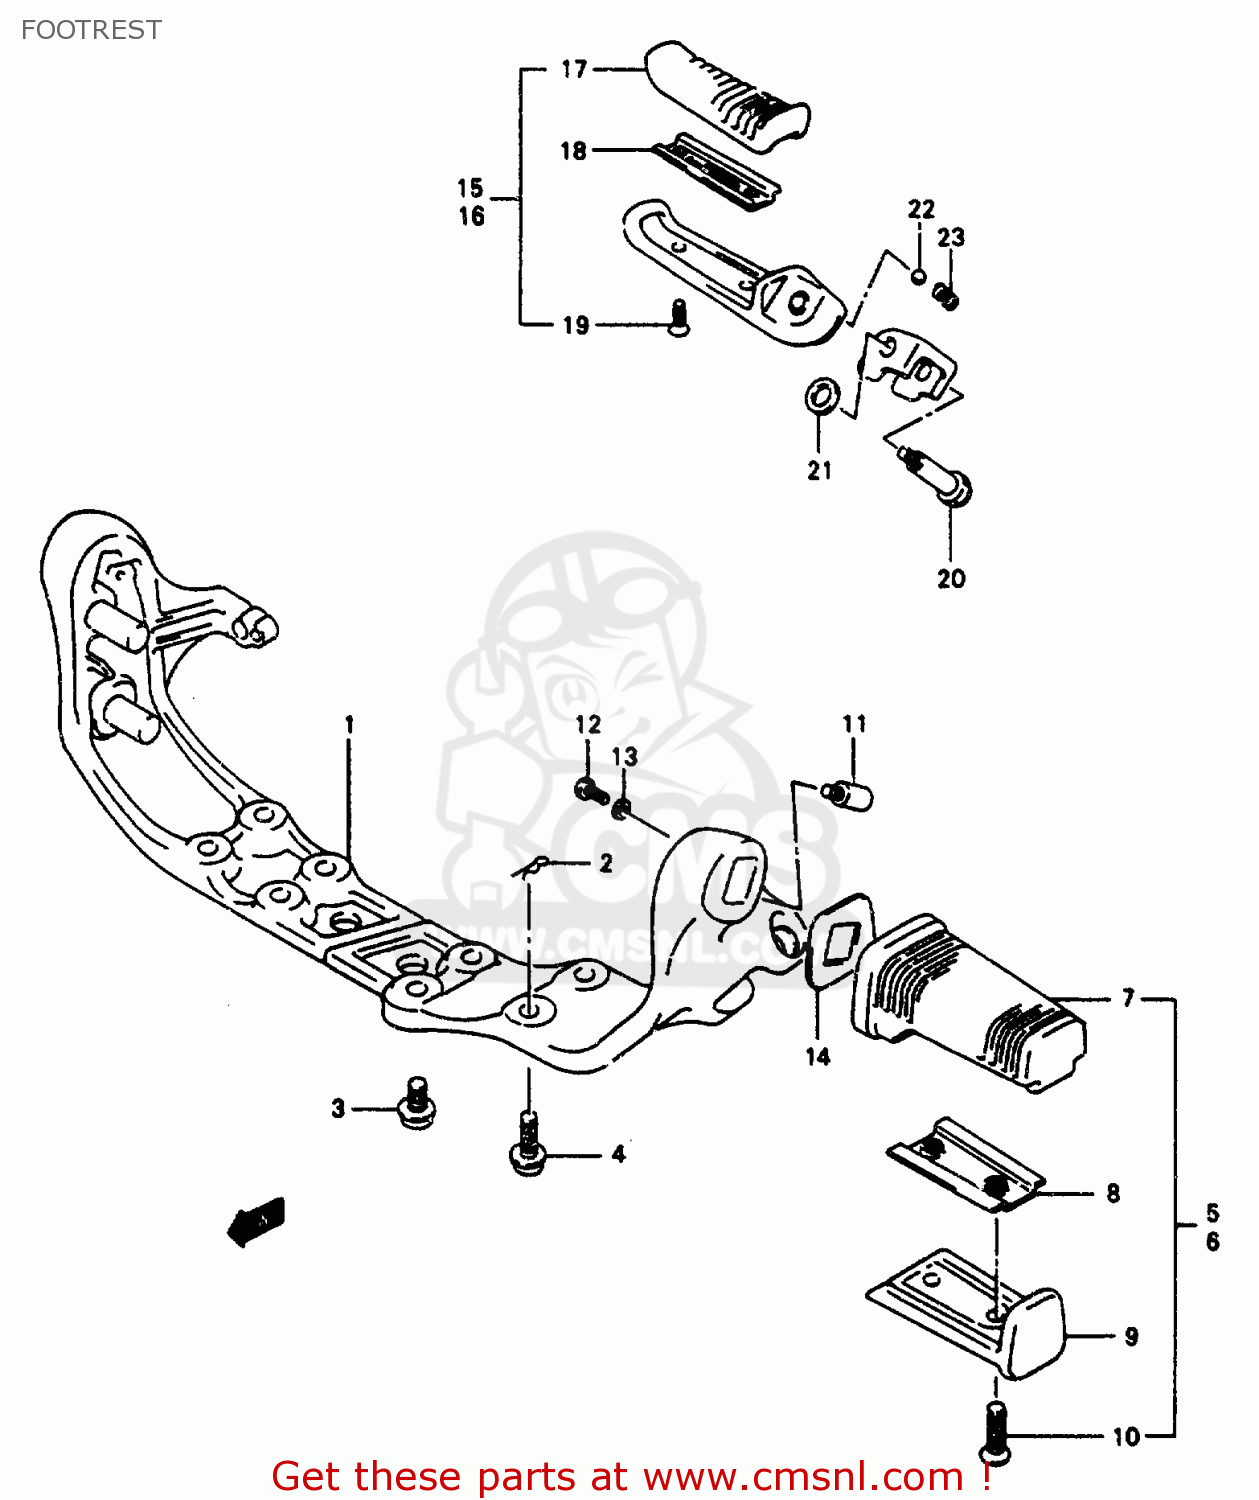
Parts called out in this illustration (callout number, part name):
1	BRACKET,FR FOOTREST
2	SNAP
3	BOLT
4	BOLT(8X25)
5	FOOTREST ASSY,FR,R
6	FOOTREST ASSY,FR,L
7	RUBBER,FR FOOTREST
8	PLATE,RUBBER STOPPER
9	COVER,FR FOOTREST
10	SCREW(5X20)
11	BOLT,FRONT FOOTREST
12	BOLT
13	WASHER,LOCK
14	WASHER,FR FOOTREST
15	FOOTREST ASSY RH
16	FOOTREST ASSY PILLION LH
17	RUBBER,PILLION FOOTREST
18	PLATE,RUBBER STOPPER
19	SCREW(5X16)
20	BOLT(6X34.5)
21	SHIM
22	BALL
23	SPRING
